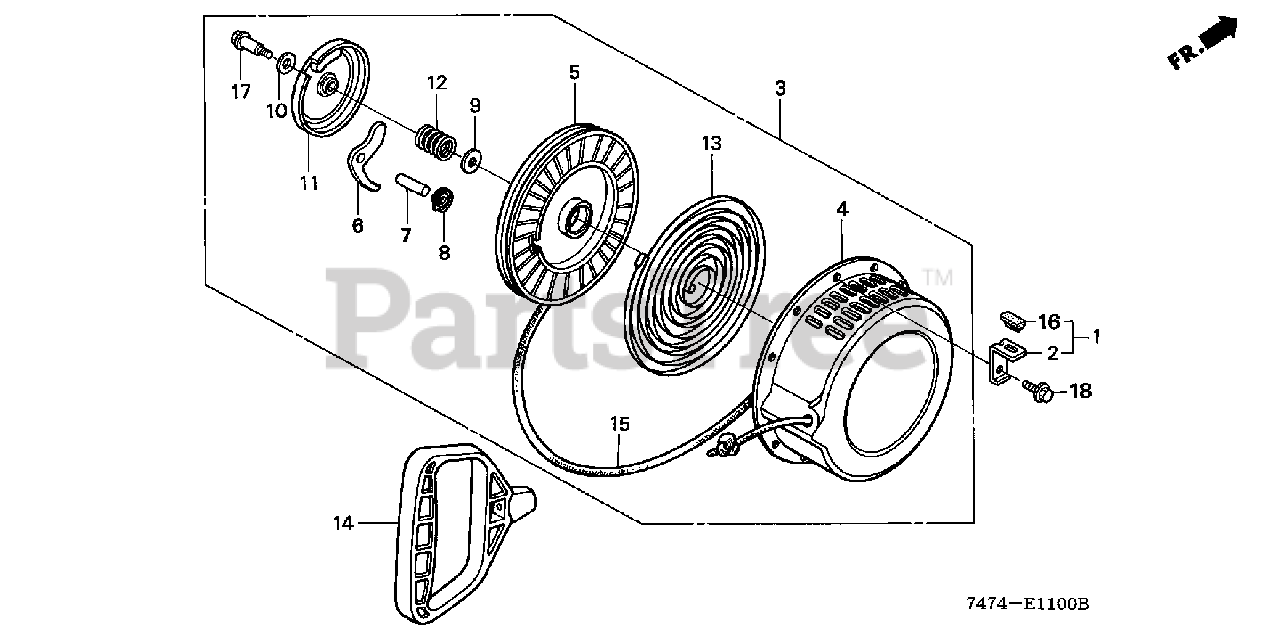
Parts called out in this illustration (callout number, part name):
1	STAY ASSY., FUEL TANK
2	STAY, FUEL TANK
3	STARTER ASSY., RECOIL *R8* (BRIGHT RED)
4	CASE, STARTER *R8* (BRIGHT RED)
5	REEL, STARTER (NOT AVAILABLE)
6	RATCHET, STARTER
7	SHAFT, RATCHET
8	PLATE, GUIDE
9	PLATE A, FRICTION
10	PLATE B, FRICTION
11	COVER, REEL STARTER
12	SPRING, FRICTION
13	SPRING, RETURN
14	GRIP, STARTER
15	ROPE, STARTER (#5X73") (NA USE ALT:08550-ZG921-11)
16	STOPPER, DISCHARGE GUARD
17	BOLT, REEL COVER
18	BOLT, FLANGE (6X8)
